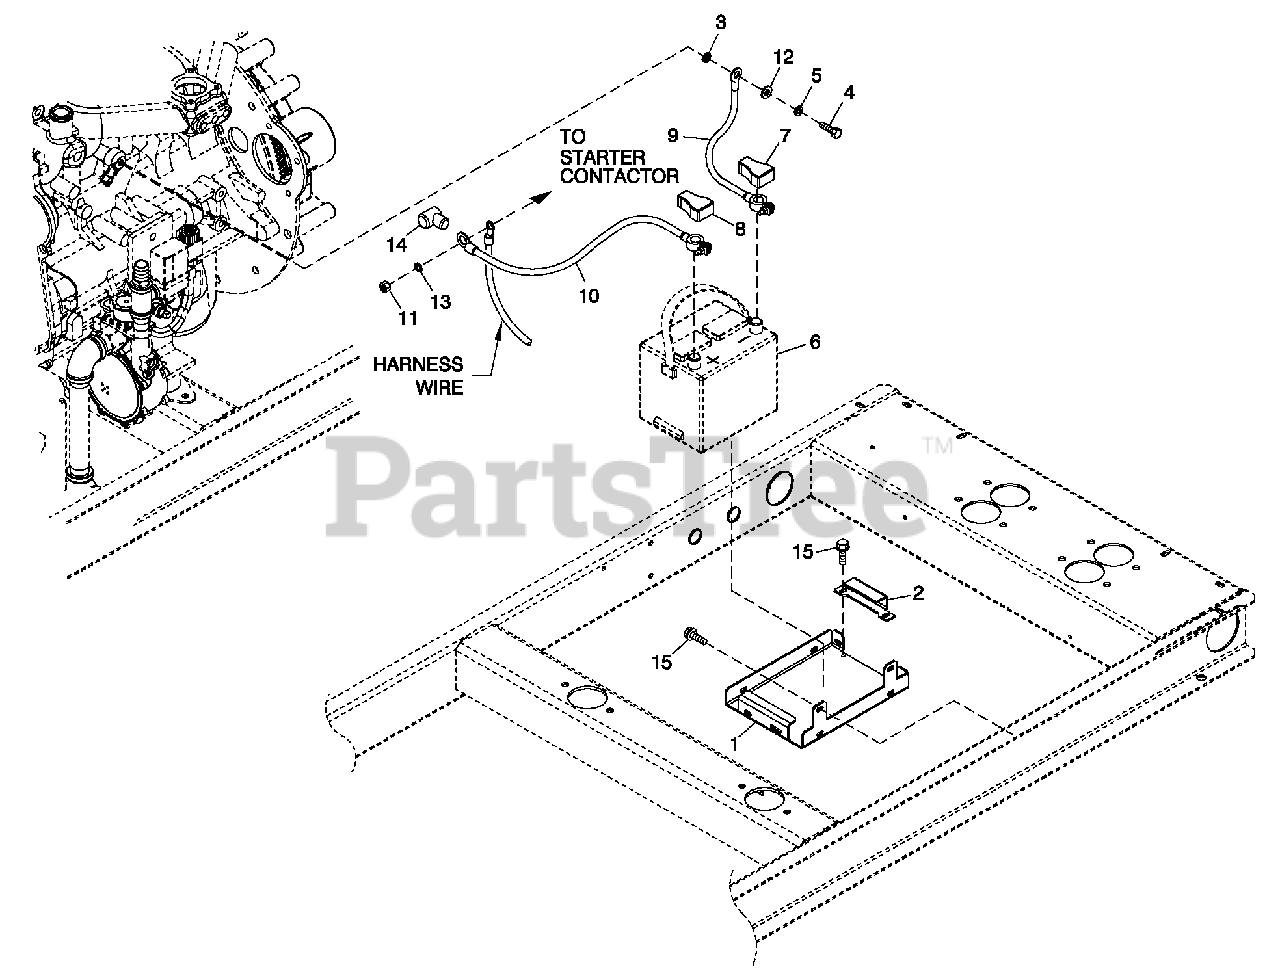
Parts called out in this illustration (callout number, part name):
1	BATTERY TRAY, C1 & C2
2	STRAP BATTERY RETAINMENT
3	WASHER SHAKEPROOF EXT 7/16 STL
4	SCREW HHC M10-1.25 X 25 C8.8
5	WASHER LOCK M10
6	BATTERY 12VDC 75-AH 26 (SOLD AS AN OPTION)
7	BATTERY POST COVER RED +
8	BATTERY POST COVER BLK -
9	CABLE BATTERY BLACK #1 X 30.00
10	CABLE BATTERY RED #1 X 21.00
11	NUT HEX M8-1.25 G8 YEL CHR
12	WASHER FLAT 3/8-M10 ZINC
13	WASHER SHAKEPROOF EXT 5/16 STL
14	BOOT CONTACTOR CABLES
15	SCREW THF M6-1 X 16 N WA Z/JS
